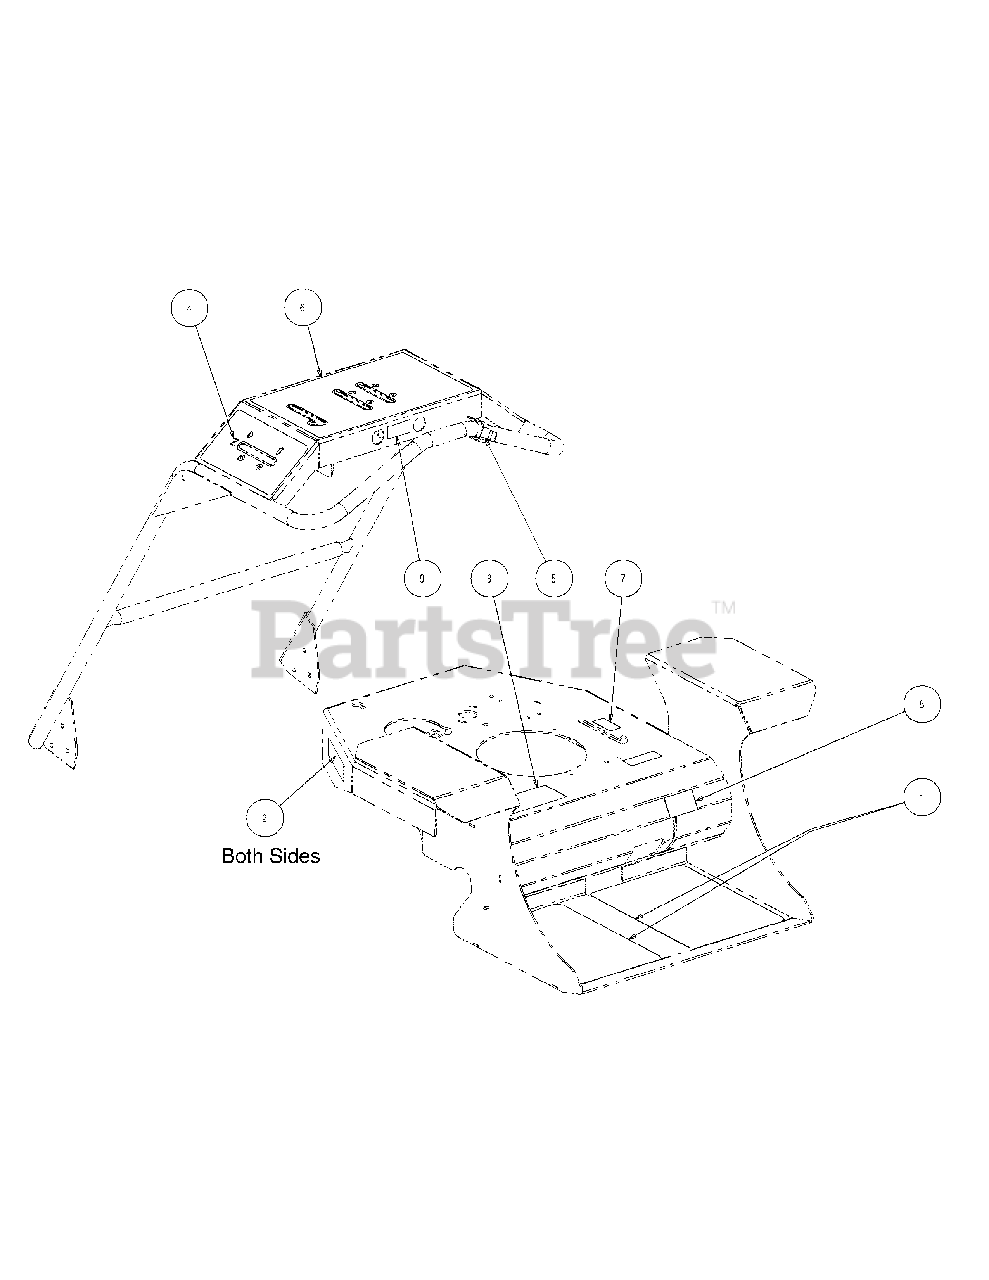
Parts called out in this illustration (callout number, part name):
1	Foot pad-Abrasive
2	Decal, Cub Cadet Commercial
3	Decal, Cub Cadet Commercial, Small
4	Decal, Throttle
5	Decal, Speed Control
6	Decal, Operator Panel
7	Decal, Neutral
8	Decal, Parking Brake
9	Decal, Fwd/Rev
